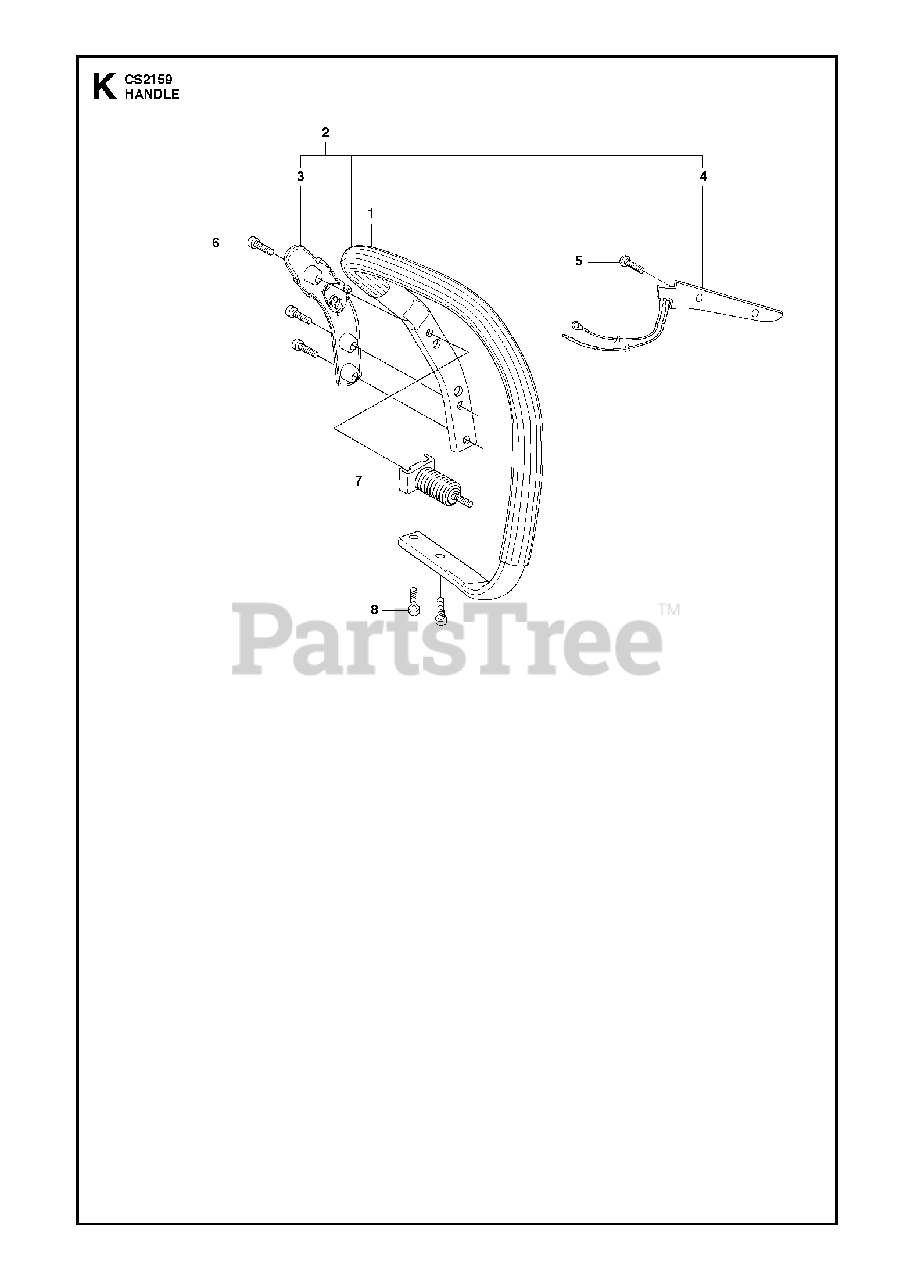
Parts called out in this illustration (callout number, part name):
1	FRONT HANDLE
2	FRONT HANDLE
3	SWITCH OF HEATING
4	HANDLE CIRCUIT
5	SCREW
7	VIBRATION ABSORBER
8	SCREW IHSCFT
